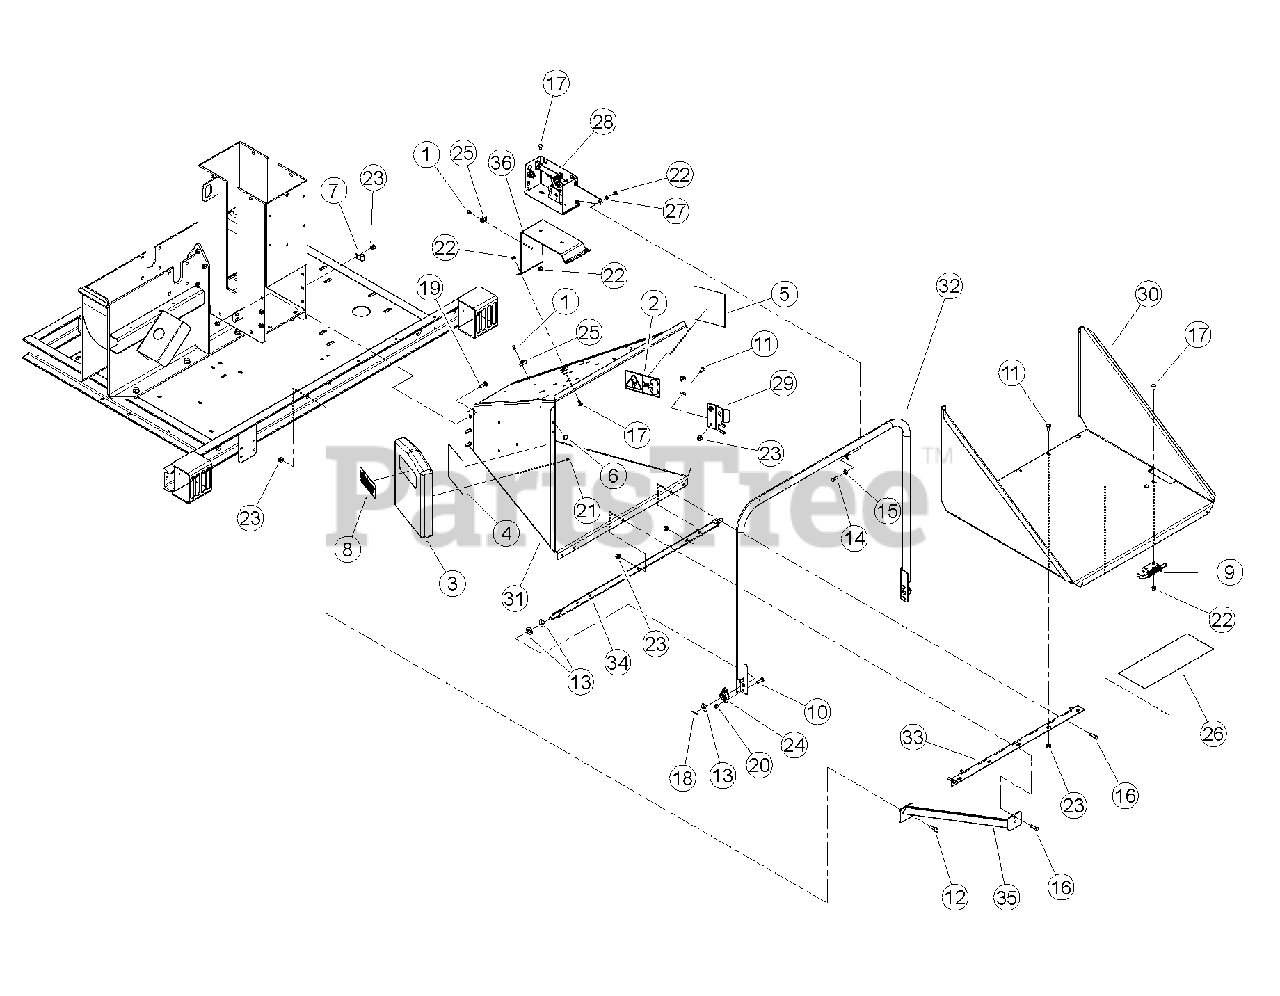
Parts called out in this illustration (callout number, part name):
1	RIVET, 1/4 X 3/4 ST POP
2	DECAL, BLADE DANGER ISO
3	CONTAINER, INSTR. MANUAL
4	DECAL, FEED POSITION
5	DECAL, FEED POSITION
6	BUMPER, RUBBER
7	CLAMP, 9/16 COATED
8	DECAL, MUTILINGUAL MANUAL
9	LATCH, RH HINGE
10	BOLT, 3/8 X 1 HEX HD GR5 ZP
11	BOLT, 3/8 X 1" GR5 CRG NC ZP
12	BOLT, 3/8 X 1-1/4 FLANGE NC
13	WASHER, 5/8" SAE FLAT ZP
14	BOLT, 5/16 X 1" GR5 HHCS NC ZP
15	WASHER, 5/16" FLAT ZP
16	BOLT, 3/8 X 1-1/4" HEX HD GR5 ZP
17	BOLT, 5/16 X 3/4 GR5 CRG NC ZP
18	PIN, 1/8 X 1.00 ZP COTTER
19	BOLT, 3/8 X 1-1/4" GR5 CRG NC ZP
20	NUT, 3/8" NE NYLOCK ZP
21	RIVET, 1/4 X 1/2 DOME HD BLIND SS
22	NUT, 5/16-18 NYLOCK-FLANGE
23	NUT, 3/8-16 NYLOCK FLANGE
24	BEARING, SIDE FLANGE MOUNT 5/8"
25	CLAMP, CABLE MOUNT
26	DECAL, BEARCAT WEB
27	SPACER, IDLER PIVOT
28	ASSEMBLY, SWITCH BOX
29	PLATE, TRAY STOP
30	WELDMENT, CHUTE EXTENSION TRAY
31	WELDMENT, BIG CHIPPER CHUTE
32	WELDMENT, CONTROL ARM
33	HINGE, EXTENSION TRAY
34	WELDMENT, CONTROL PIVOT
35	WELDMENT, CHUTE SUPPORT
36	MOUNT, SWITCH BOX
